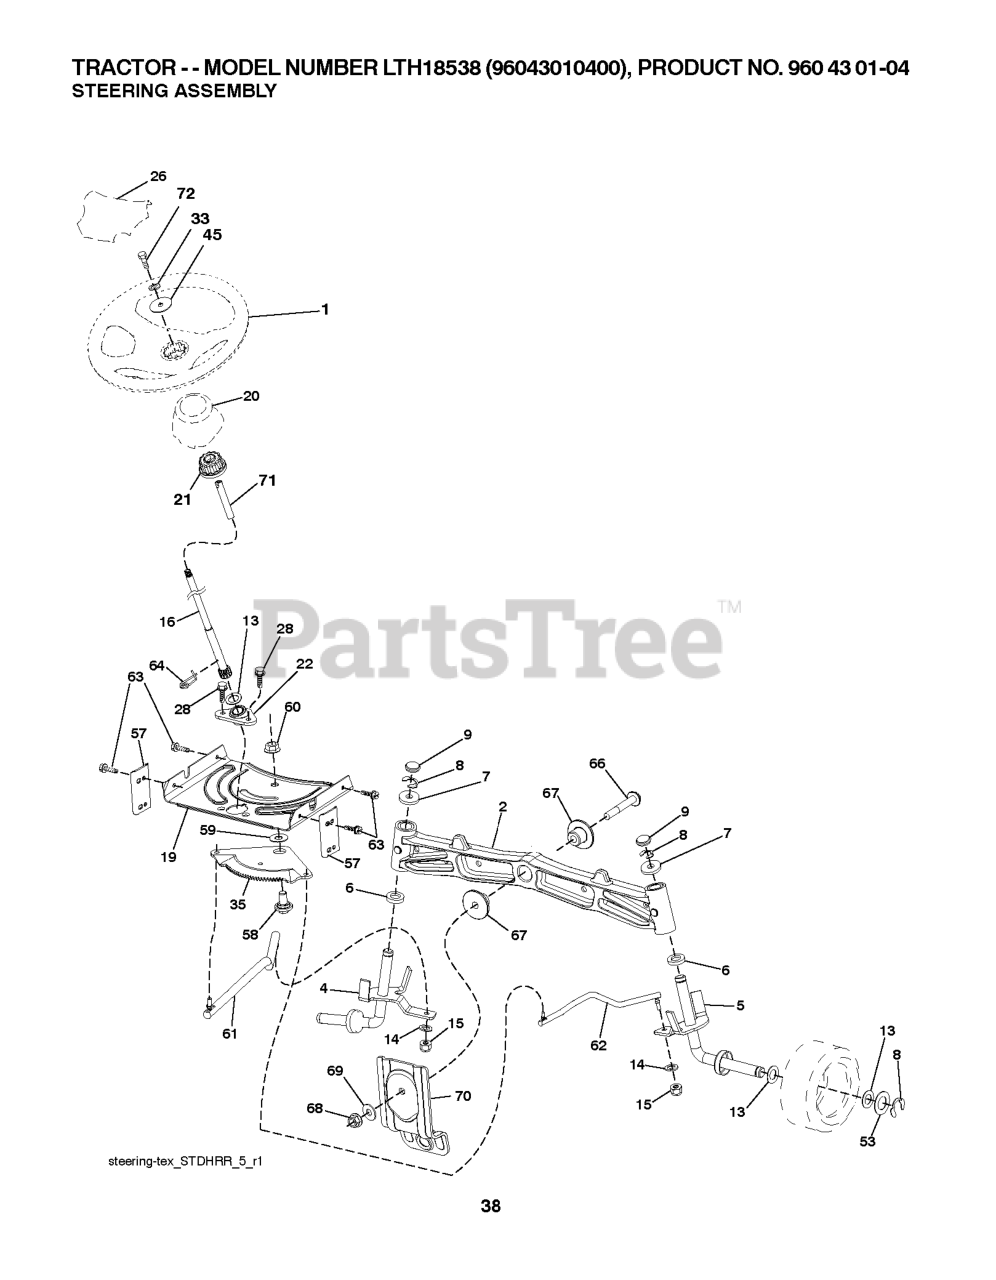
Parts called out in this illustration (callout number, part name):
1	WHEEL STEERING
2	AXLE.CAST.IRON
4	SPINDLE.WELDED.LH.15"TEX
5	SPINDLE.WELDED.RH.15"T
6	THRUST WASHER
9	CAP.SPINDLE.BLACK
14	WASHER, LOCK 3/8
15	NUT CROWNLOCK 3/8-24
16	SHAFT.STEER.3/4.NON-PLATED.TEX
19	PLATE.STEER.DDL.NLT/NG
20	BOOT, STEERING
21	ADAPTER, WHEEL STNG..
22	STEERING.SUPT.LOWER.
26	RP INSERT.CAP.WHL.STRG.HUSQ.
28	SCREW, 3/8-16X3/4
33	WASHER.LOCK.HVY.HLCL.SPR.5/16
35	GEAR.SECTOR.PLATE.DDL.
45	WASHER.11/32
53	WASHER.HARDENED
57	BRACKET.UPSTOP.TEX
58	BOLT.SHOULDER.SECTOR.P
59	WASHER.THURST.SECTOR.S
60	NUT FLANGE LOCK 5/8-11
61	DRAGLINK.LH.BALLSTUD.D
62	DRAGLINK.RH.BALLSTUD.D
63	SCREW
64	RETAINER.CLIP.SPRING.S
66	BOLT HEX FGHD 7/16-14 X 3 SERR
67	BUSHING.PM.FRONT AXLE
68	NUT.LOCK.FLANGE.7/16
69	WASHER.1.5X.505X.118
70	BRKT.DECK.SUSPENSION.F
71	SHAFT.EXTEN.STRG.SPLINE
72	BOLT 5/16-18 X 4 W/PATCH
